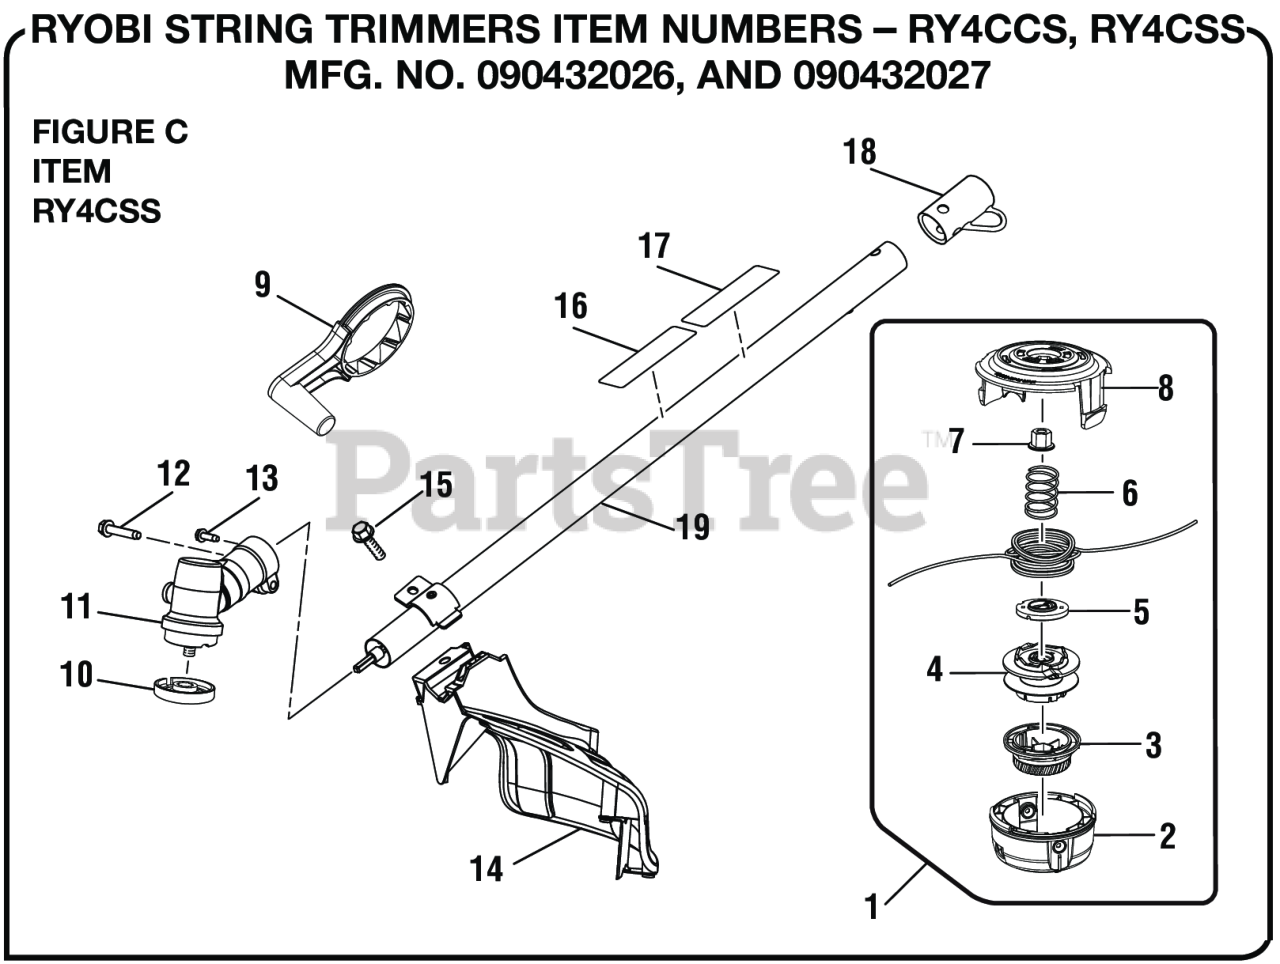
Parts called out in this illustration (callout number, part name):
1	Trimmer Head Assembly (.095)
2	Lower Housing
3	Bump Knob (Green)
4	Spool Assembly
5	String Guide
6	Compression Spring
7	Hex Nut (M8, Left Hand Threads)
8	Upper Housing
9	Crank Handle Assembly
10	FLANGED WASHER
11	Gear Case Assembly
12	Screw (1/4-20 x 1-1/4 in., Hex Washer Hd. S.T.)
13	Screw w/Washer (10-24 x 5/8 in., Hex Hd. T.F.)
14	Grass Deflector Assembly
15	SCREW (#1/4-20 X 1-1/4 in. HEX WASHER HD.)
16	Ryobi EXPAND-IT Label
17	Warning Icon Label
18	Storage Hanger Cap
19	Straight Shaft Assembly
